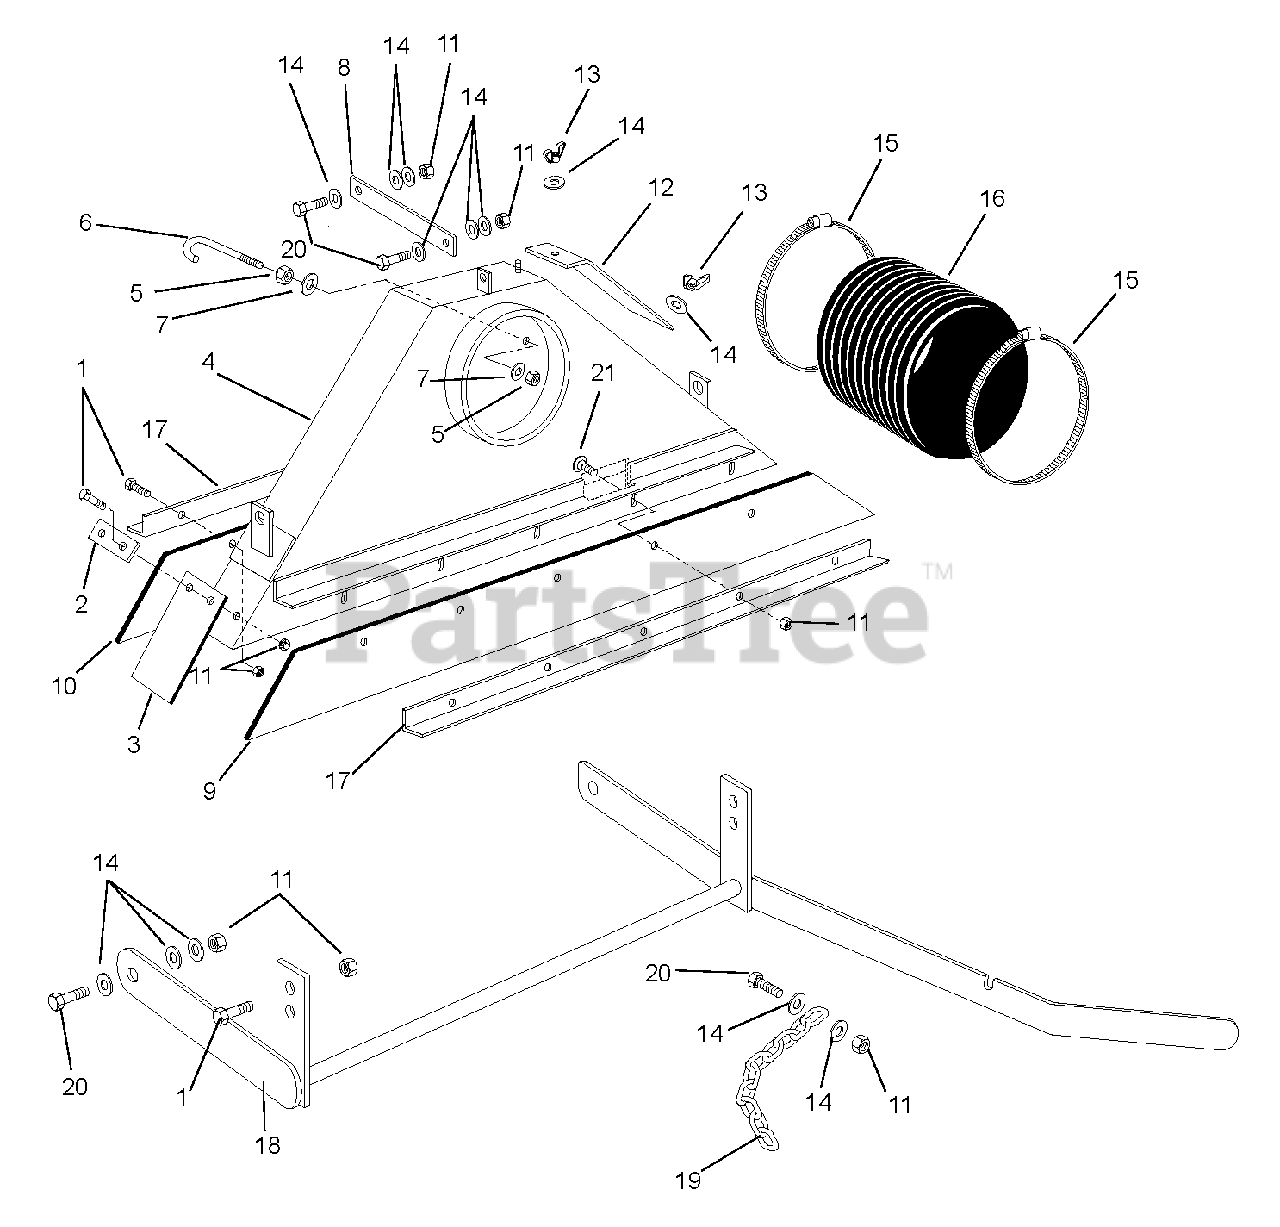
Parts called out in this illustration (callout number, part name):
1	Cap Screw, Hex Head .38-16 x 1.00
2	End, Bolting Strip
3	End Cap, Flex Skirt
4	Weldment, Scoop
5	Nut, Hex .50
7	Washer, Flat .50
8	Brace, Scoop Stabilizer
9	Flex Skirt, Front
10	Flex Skirt, Rear
11	Nut, Nylock .38-16
12	Side Cover, Scoop
13	Wing Nut, .38-16
14	Washer, Flat .38
15	Clamp, Worm Drive 13 Inch
16	Hose, Flex 12 Inch
17	Retainer Strip
18	Weldment, Lift
19	Support Chain 12 Link 1/4"
20	Cap Screw, Hex Head .38-16 x 1.25
21	Bolt, Carriage .38-16 x 1.00
